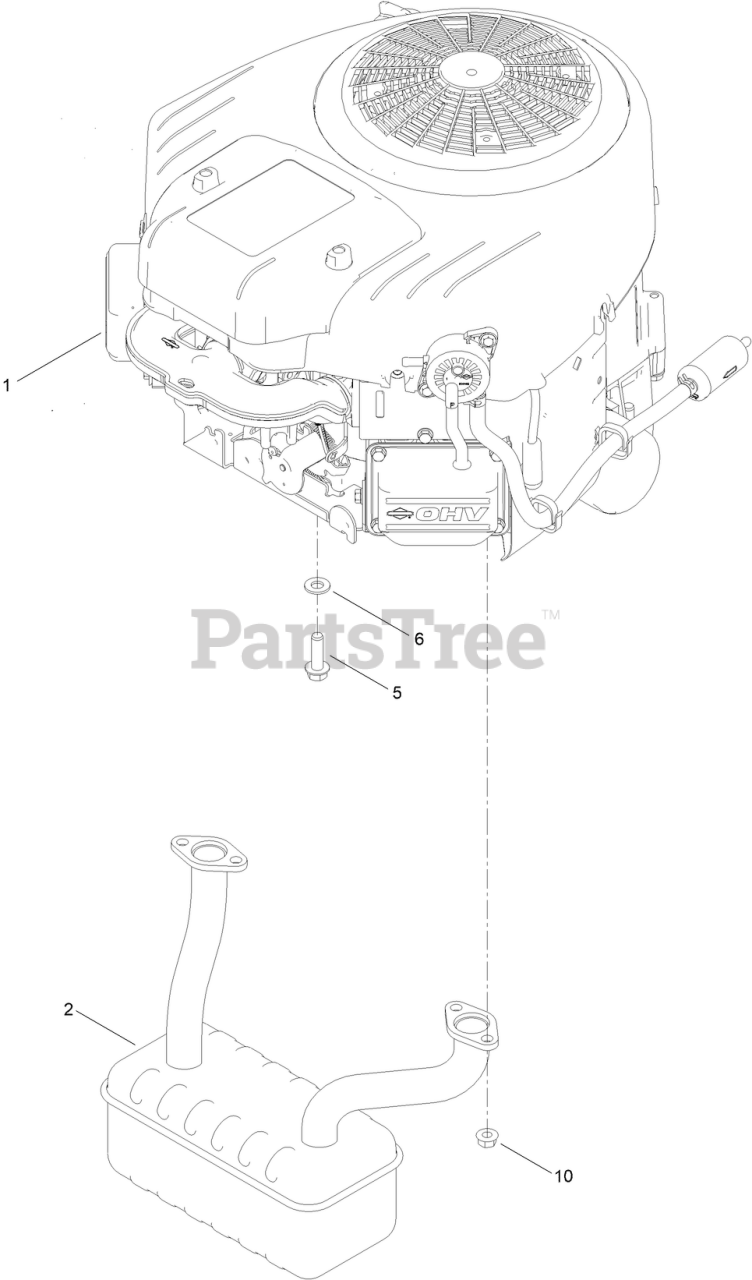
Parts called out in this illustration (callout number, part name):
1	ENGINE-BS EXI
2	MUFFLER
5	SCREW-HWH, THD ROLL
6	WASHER-FLAT
10	NUT-HF
